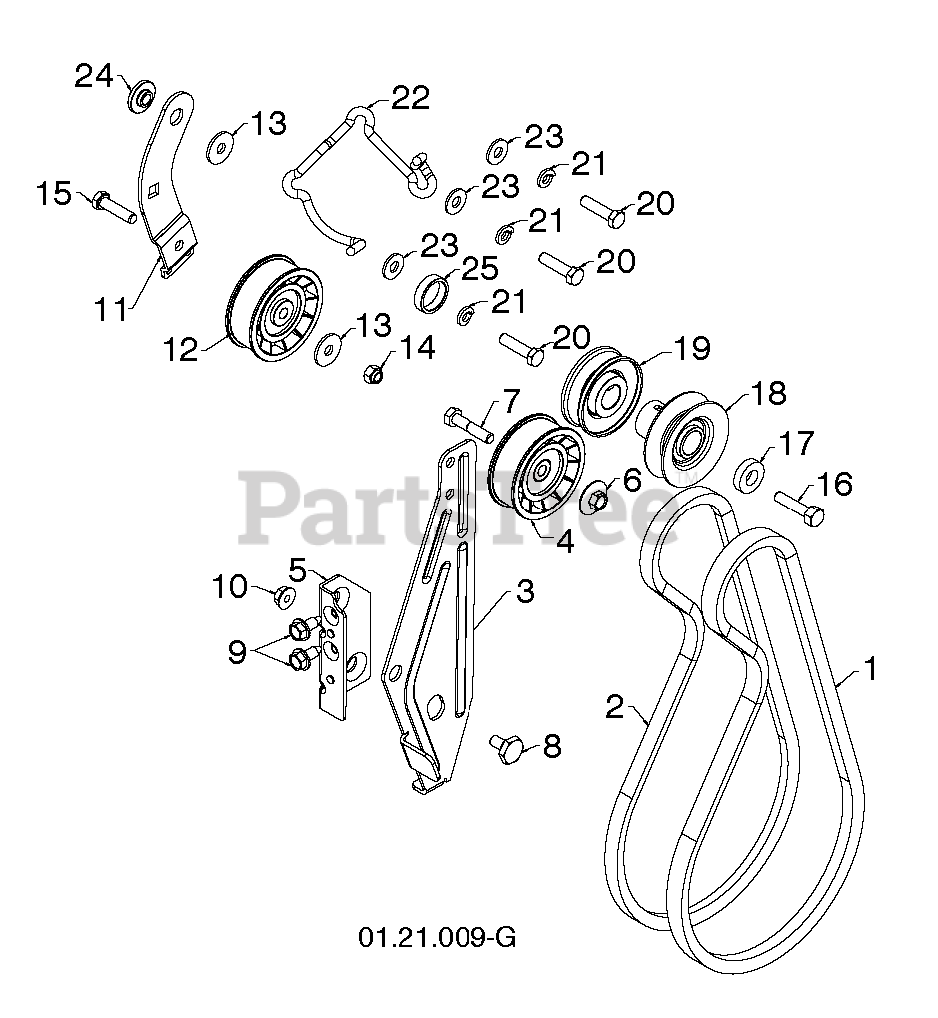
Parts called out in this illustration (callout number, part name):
1	BELT.V.IMPELLER
2	V-BELT.TRACTION.HYDRO
3	ARM.IDLER.BRAKE.
4	PULLEY.W/SPACER.2.75
5	RP BRACKET.IDLER.PIVOT
6	NUT.FLANGE.HEX.5/16X18.BLACK
7	HEX BOLT
8	BOLT.SHOULDER.1/2X12
9	BOLT.HEX.HD.WASHER.5/16-18X.75
10	NUT.LOCK.5/16-18
11	ARM, IDLER
12	PULLEY.W/SPACER.2.75
13	STEEL WASHER
14	NUT.71038.31-18.HEX.NYLOCK
15	BOLT.5/16-18X1-1/4 FULL.THREAD
16	SCREW, HEX HD 3/8-24 X 1-3/8
17	WASHER, FLAT 3/8
18	PULLEY.IMPELER.
19	PULLEY,ENGINE TRACTION DRIVE
20	CAPSCREW.HEXHD.5/16X1.25.
21	WASHER.LOCK.HVY.HLCL.SPR.5/16
22	GUIDE.BELT.HYDRO.LS.SNOW
23	WASHER.20X8.5
24	RP BUSHING, IDLER PIVOT
25	SPACER.ENGINE.PULLEY
